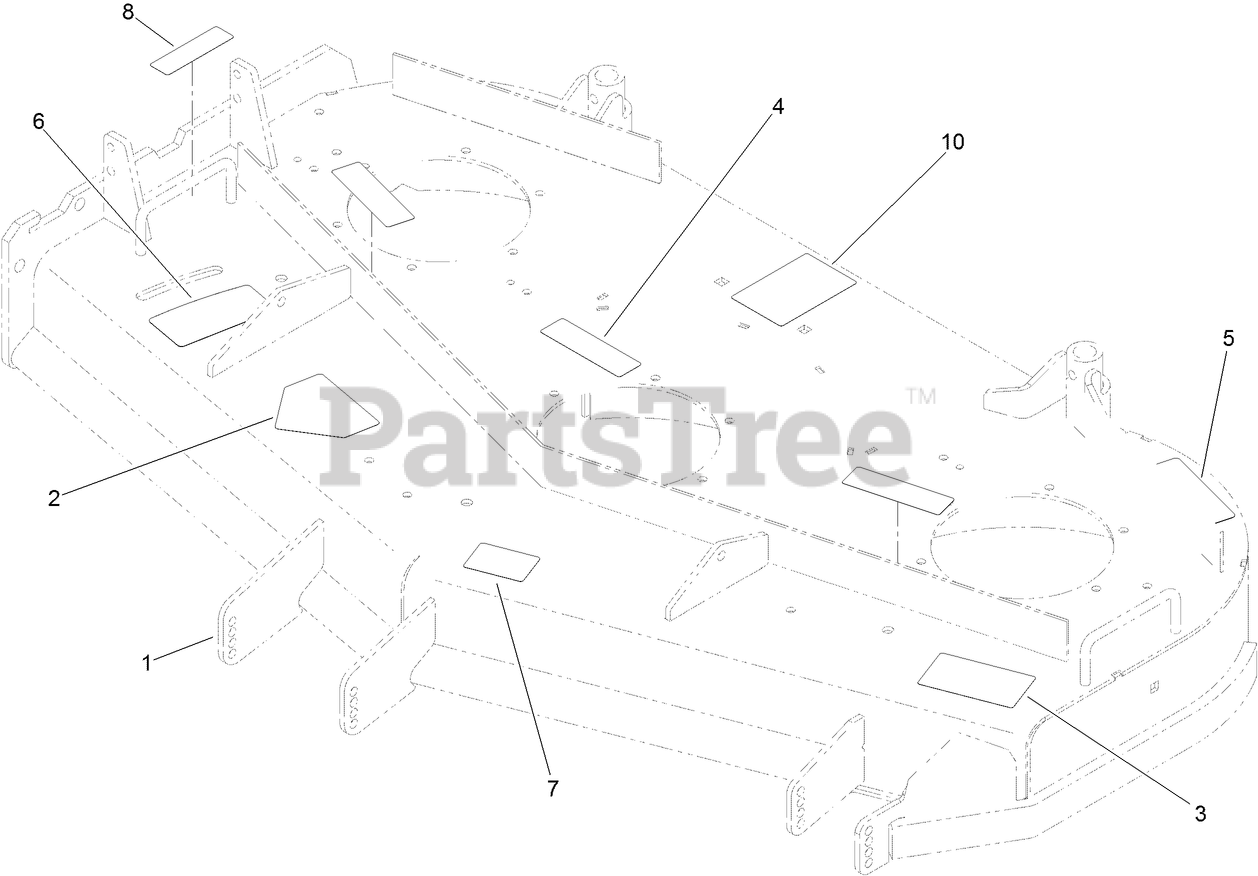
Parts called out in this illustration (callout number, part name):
1	48 INCH DECK ASM
2	DECAL-DANGER
3	DECAL-DANGER
4	DECAL-MISSING, COVER
5	DECAL-TORQUE, BLADE BOLT
6	DECAL-ADJUSTMENT, BAFFLE
7	DECAL-SCALP, ANTI
8	DECAL-WARNING, DEFLECTOR
10	DECAL-ROUTING, BELT
